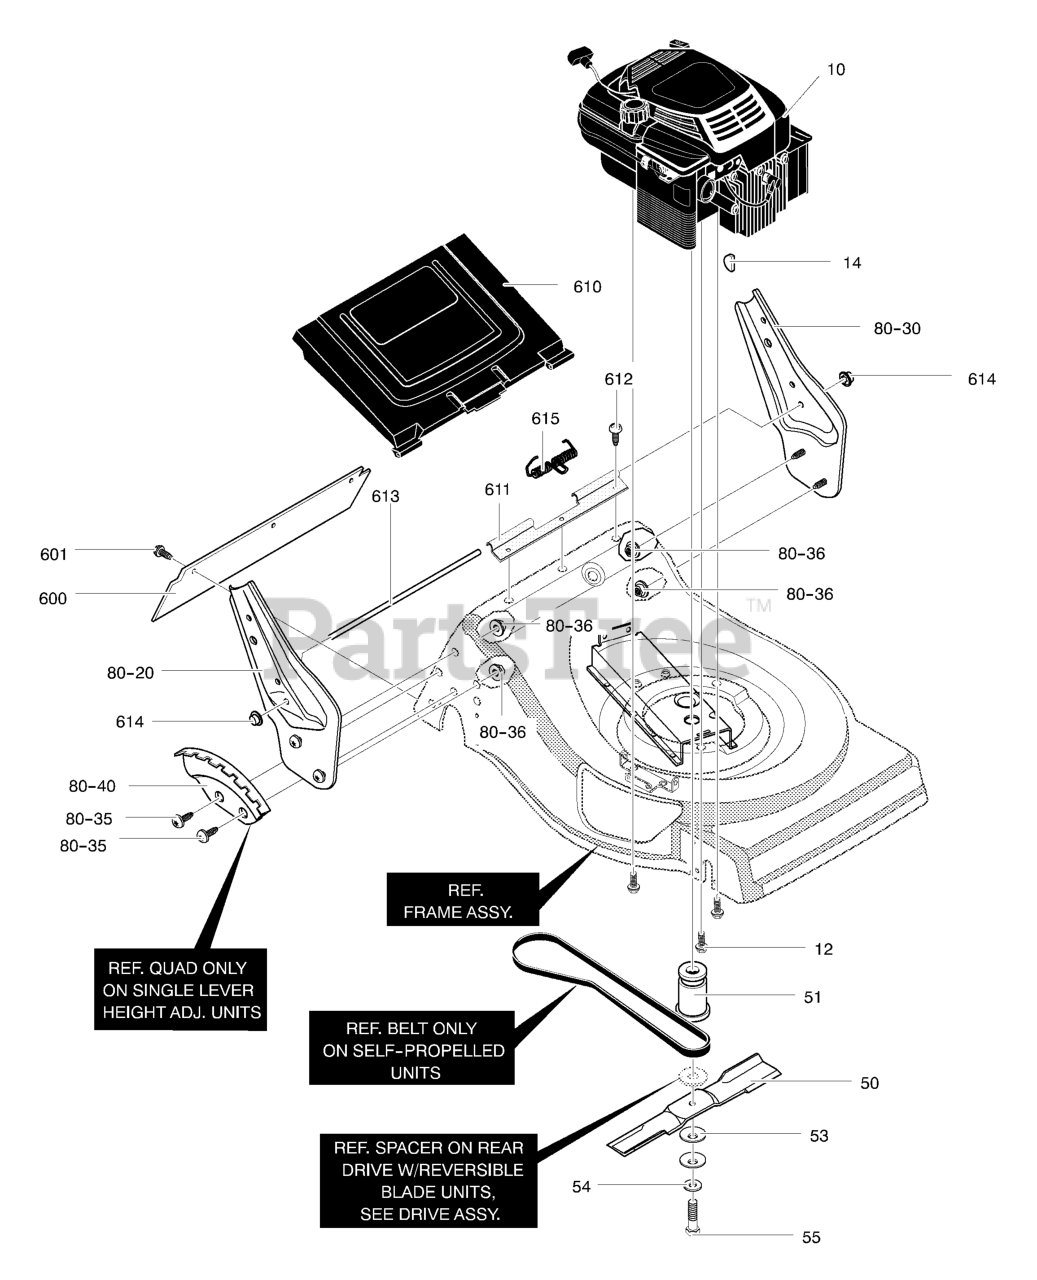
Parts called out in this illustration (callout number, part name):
10	Engine
12	Screw, 3/8-16 x 1.00
14	Key, Woodruff 505
50	Blade, 21 Inch
51	Adapter, Blade
53	Washer
54	Washer, Flat
55	Screw, 3/8-24 x 1.50
80-20	Bracket, Handle RH
80-30	Bracket, Handle LH
80-35	Screw, 5/16-18 x 0.63
80-36	Nut, 5/16-18
80-40	Quadrant, Height Adj.
600	Deflector, Rear
601	Screw, 3/8-24 x 1.50
610	Door, Rear
611	Spacer, RR Door
612	Screw, 10-16x.50
613	Rod, Pivot RR Door
614	Cap, Push On
615	Spring, Torsion
